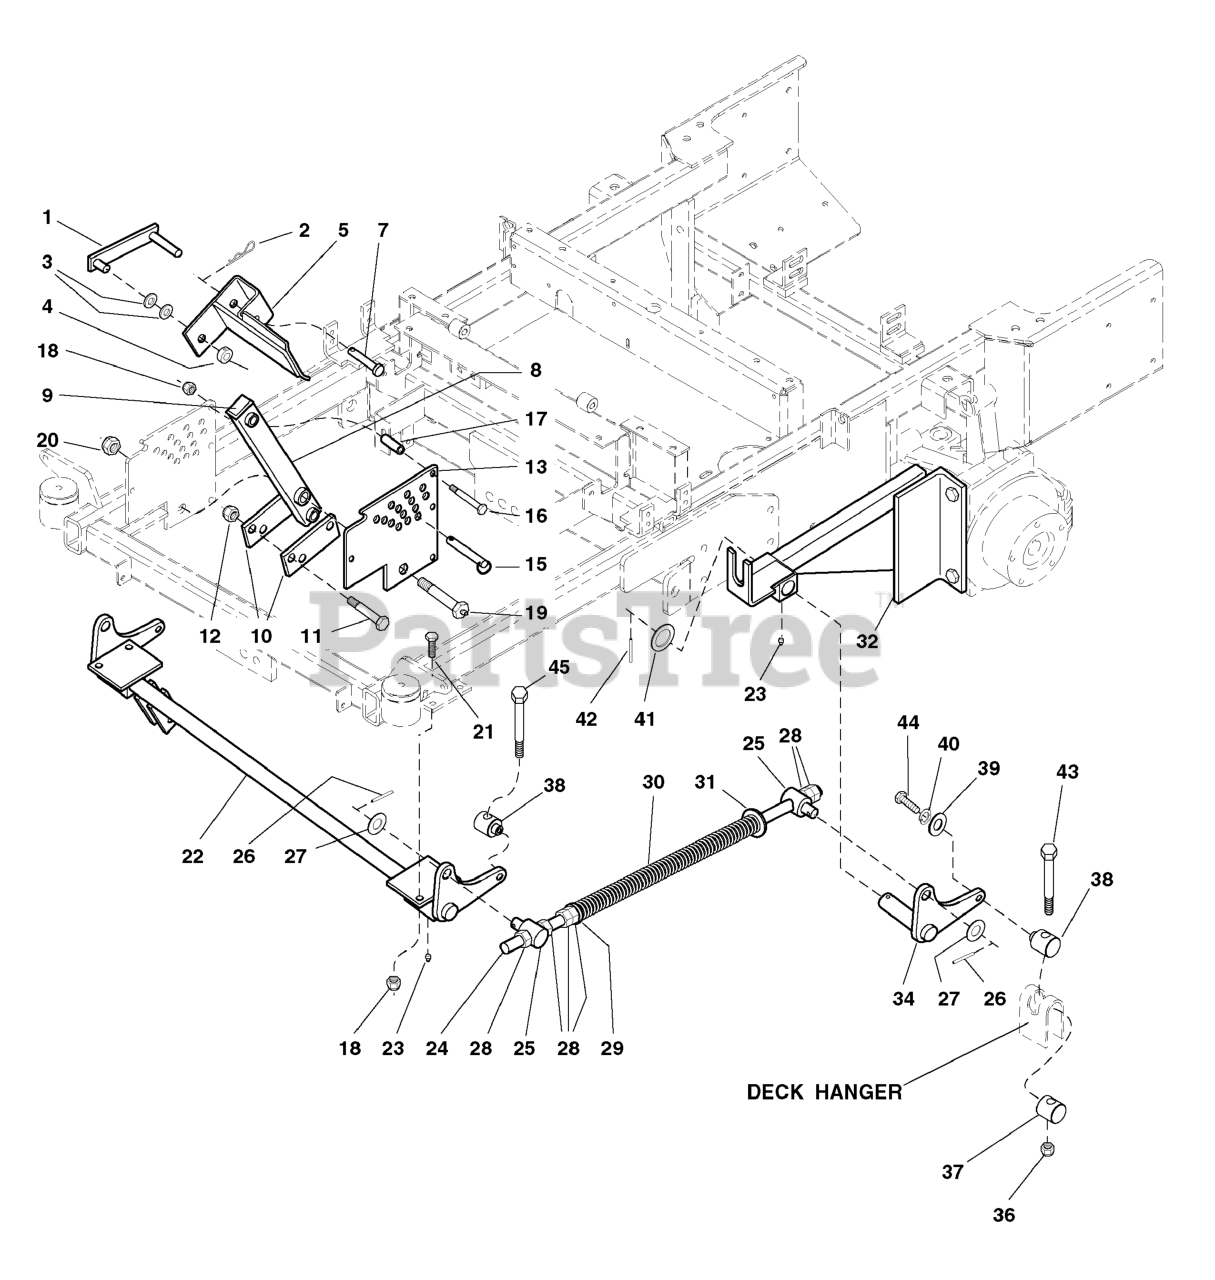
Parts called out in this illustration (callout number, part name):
1	DECK LIFT LOCK
2	HAIRPIN CLIP
3	WASHER, 1/2 SAE
4	COLLAR, 1/2" Set
5	WELD, DECK LIFT PEDAL
7	PIN, Clevis, 1/2 x 2-1/2
8	ARM, Deck Lift Pivot
10	DECK LIFT LINK
11	BOLT, 1/2-20 x 3
12	NUT, Hex, Nylon Lock, 1/2-20
13	DECK HEIGHT PLATE
15	PIN, 1/2 x 3
16	BOLT, 3/8-16 X 2-3/4" GD5 CZ
17	SPACER, .38 x .50 x 1.56
18	NUT, 3/8-16 HEX NYLON LOCK
19	LIFT PIVOT BOLT
20	NUT, 5/8-11 Hex Jam Nylon Lock
21	BOLT, 3/8-16 X 1-1/4" GD5 CZ
22	DECK LIFT SHAFT & MOUNT ASSEMBLY
23	GREASE FITTING
24	SPRING ROD
25	SPRING ROD PIVOT
26	PIN, Spring, 3/16 x 1-1/4
27	WASHER, 5/8" SAE
28	NUT, 5/8-11 Hex
29	SPACER, .63 x 1.06 x .23
30	SPRING, Deck Lift
31	WASHER, 5/8" USS
32	REAR DECK LIFT FRAME- LH
34	DECK LIFT PIVOT-LH
36	NUT, 1/2-13 HEX NYLON LOCK
37	DECK PIVOT Bushing
38	LIFT BOLT PIVOT
39	WASHER, 5/16" SAE
40	WASHER, 5/16 LOCK CZ
42	PIN, Roll, 3/16 x 1-1/2
43	BOLT, 1/2-13 x 6
44	BOLT, 5/16-24 x 3/4
45	BOLT, 1/2-13 x 6
45	BOLT, 1/2-13 x 8
